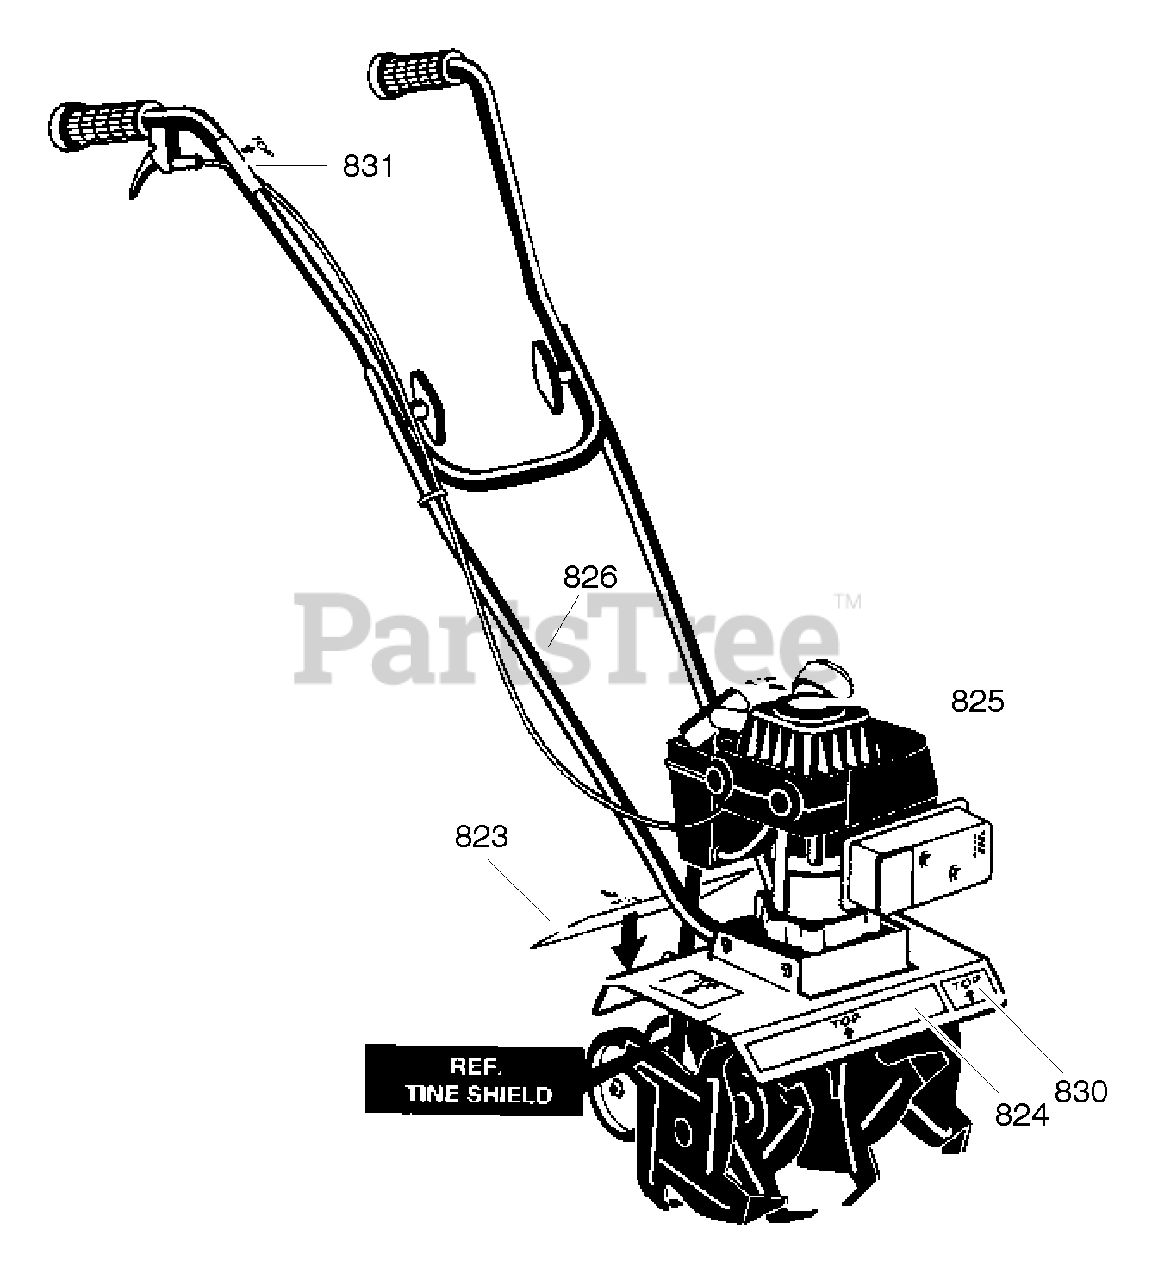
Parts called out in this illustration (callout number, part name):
823	Decal, Caution
824	Decal, Husqvarna
825	Decal, Engine Recoil
826	Decal, Hold Grip
830	Decal, CT20
831	Decal, Throttle Control
